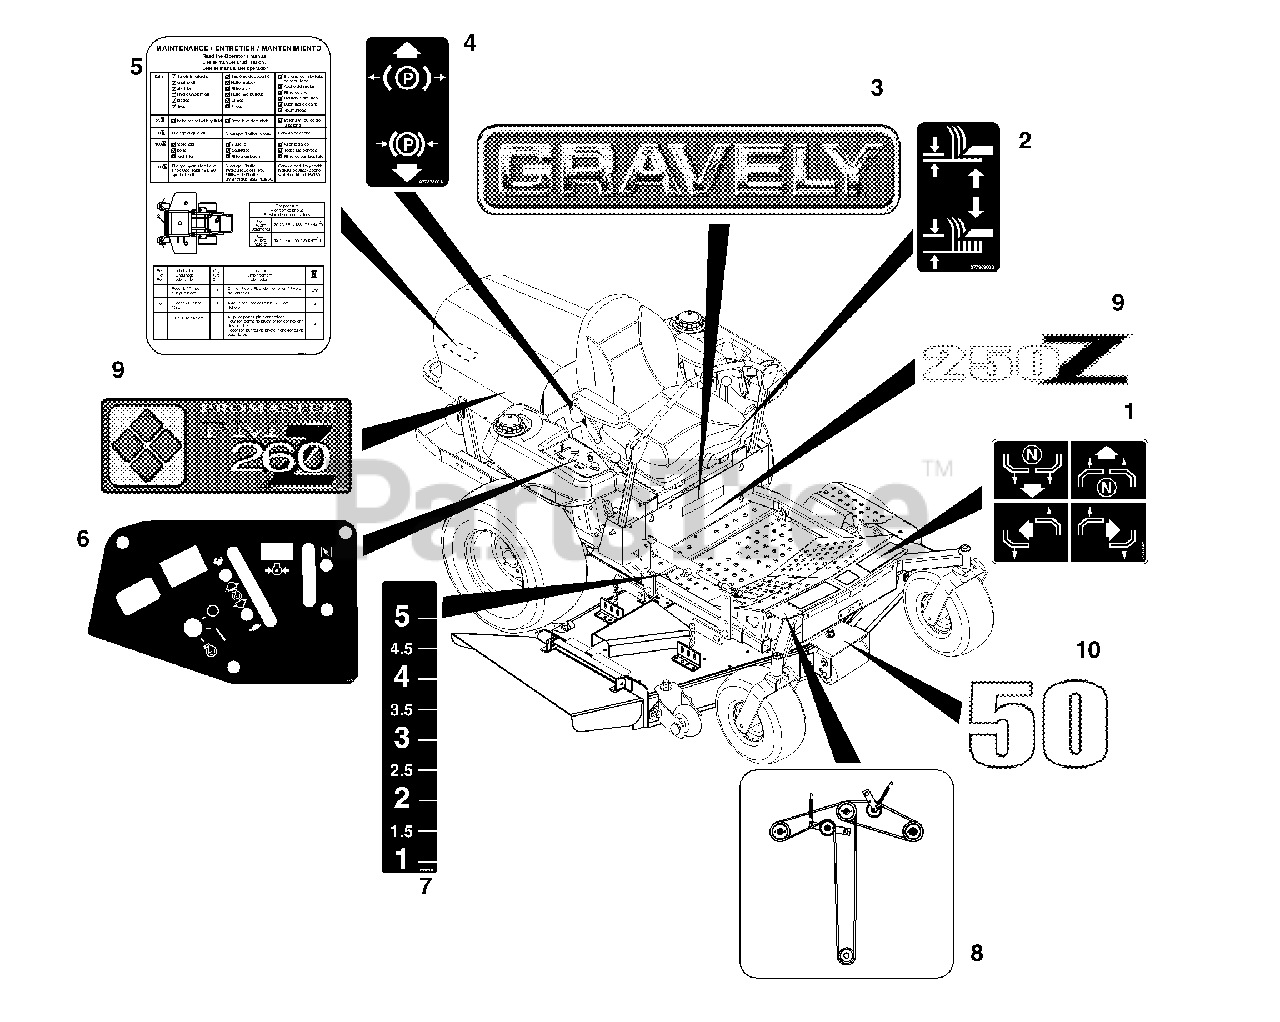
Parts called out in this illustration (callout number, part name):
1	Decal-Instructional Steering
2	Decal, Lift Lever
3	Decal, 15" Gravely Logo
4	Decal, Parking Brake Lever
5	Decal, Service Instructions
6	Decal, Control Panel
7	Decal, Height of Cut
8	Decal, Belt Diagram
9	Decal, Logo- Gravely 250Z
9	Decal, PM 260Z Logo
10	Decal, 50
10	Decal, 60
10	Decal, 72
